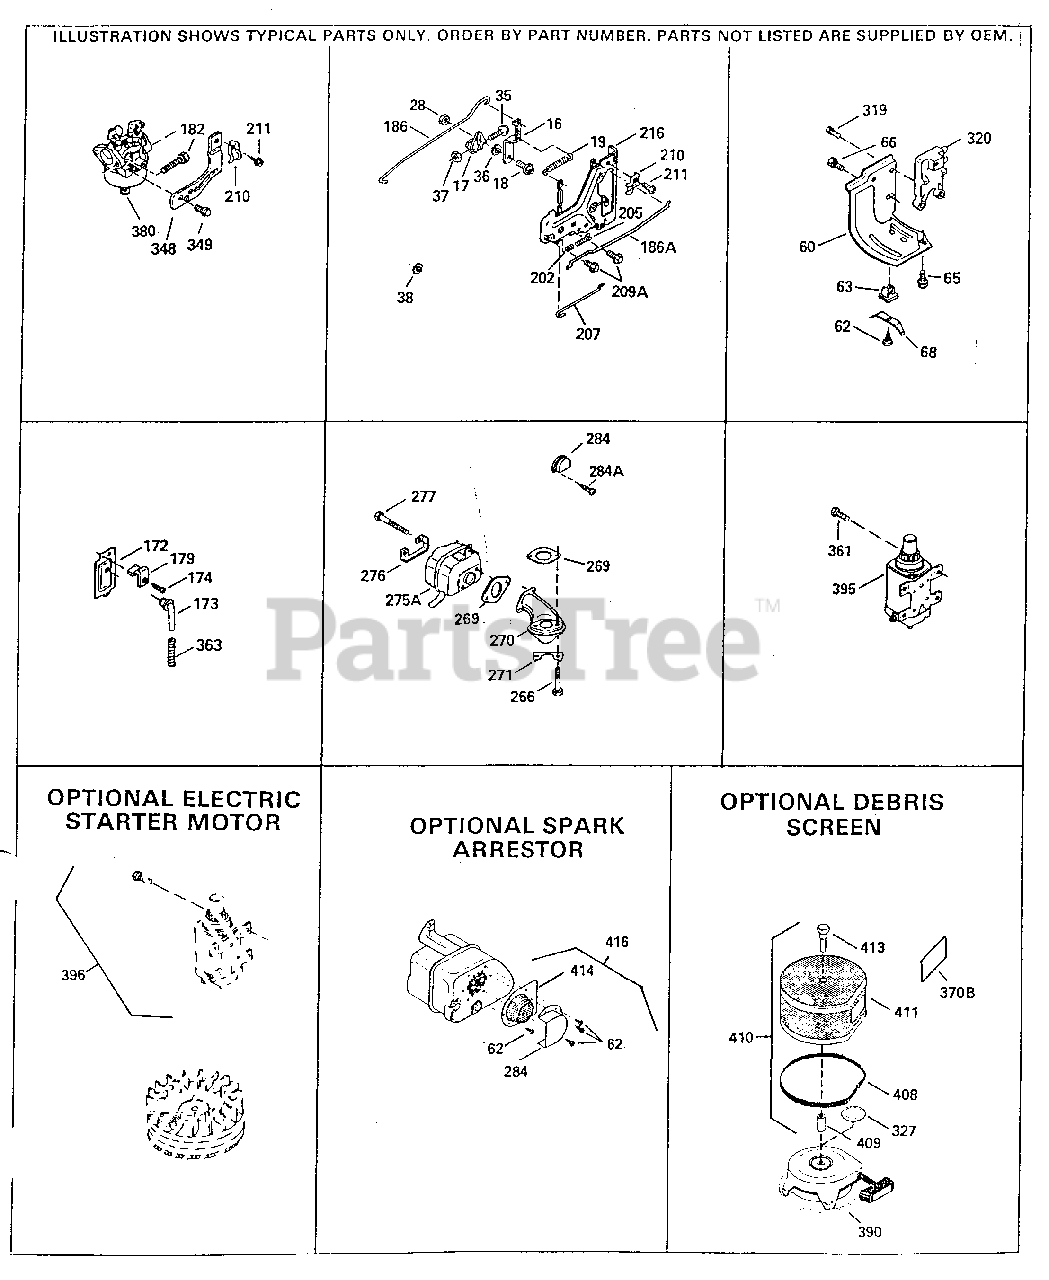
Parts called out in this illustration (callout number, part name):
16	Governor Lever
17	Governor Lever Clamp
18	Screw, 8-32 x 5/16"
19	Extension Spring
28	Lock Nut, 8-32
35	Screw, 10-32 x 3/4"
36	Lock Washer #8
37	Lock Nut, 10-32
38	Retaining Ring
60	Blower Housing Extension
65	Screw, 10-24 x 1/2"
66	Screw, T-30, 1/4-20 x 1/2"
172	Valve Cover
173	Breather Tube
174	Screw, 10-24 x 1/2"
182	Screw, 1/4-20 x 27/32"
186	Governor Link
186A	Choke Link
202	Compression Spring
205	Screw, 6-32 x 21/32"
207	Throttle Link
210	Conduit Clip
211	Screw, 10-32 x 3/8"
216	Control Bracket (Incl. 203 & 204) 5 & 206)
284	Exhaust Deflector
361	Screw, T-30, 1/4-20 x 1/2"
380	Carburetor (Incl. 184) (Refer to Divi sion 5, Section A, page A4-6 or Fiche 12, Grid F-5for breakdown)
395	Electric Starter Motor (12 Volt) (Inc l. 361) (Refer to Division 5, Section D, page 30 or Fiche 12, Grid G-12 fo r breakdown)
396	Electric Starter Motor (120 Volt) (op t ional) Engine requires a ring gear flywheel (611091 minimum) and the cy linder must have drilled and tapped s tartermounting bosses to add the elec tric starter.
414	Spark Arrestor Screen (Incl. 417) ona l)
416	Screw, 8-32 x 3/8" (Optional)
